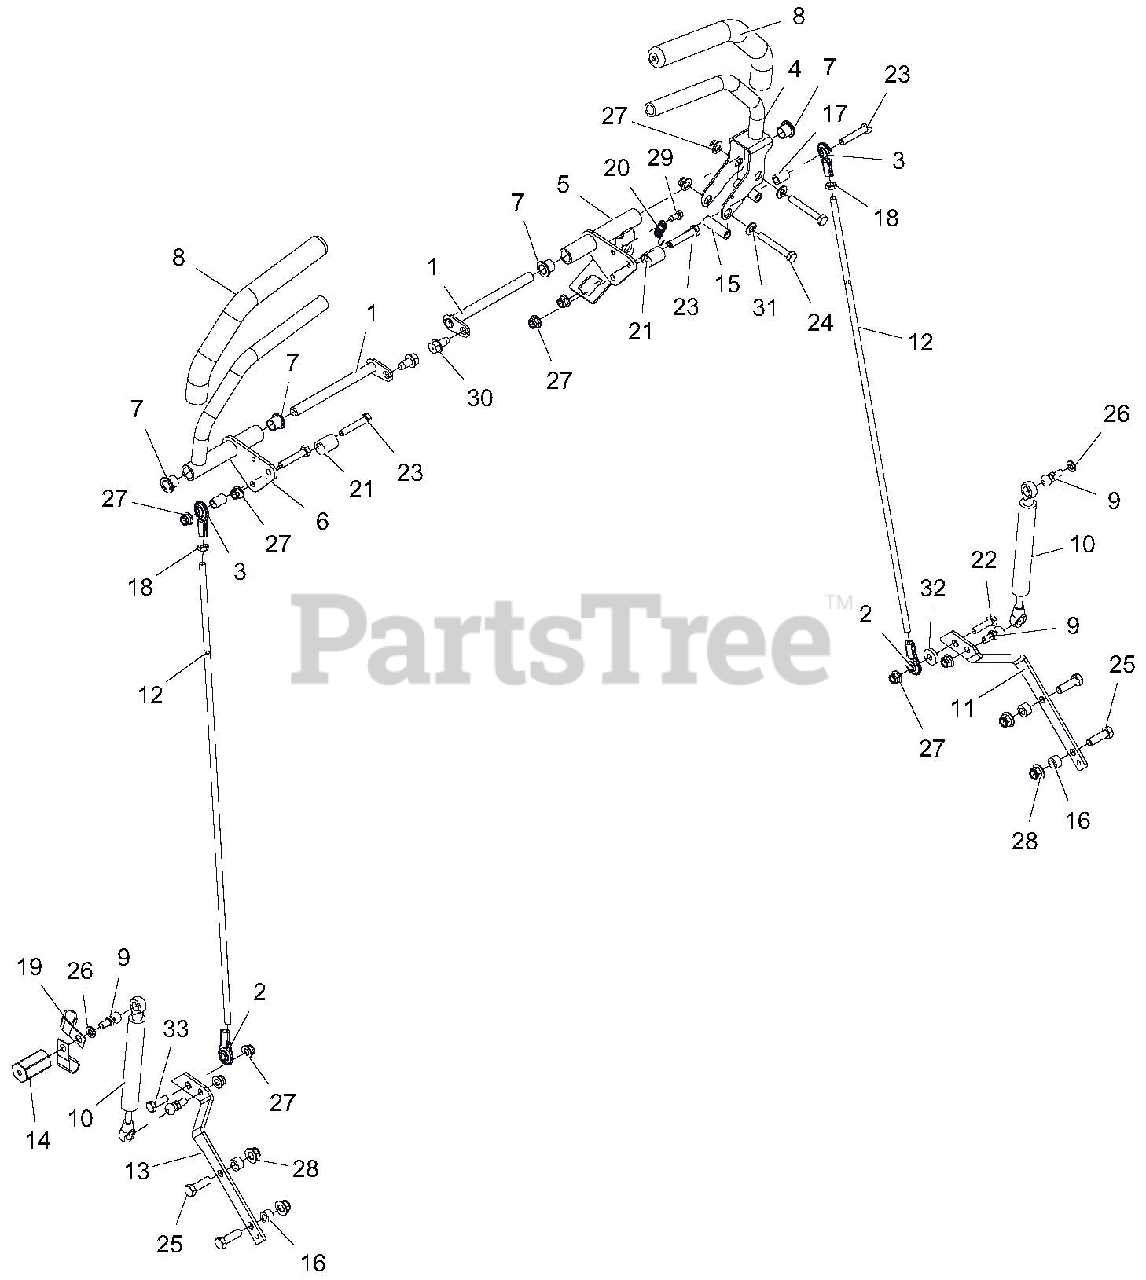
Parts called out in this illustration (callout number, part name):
1	WLDMT, PIN & LOCK
2	ALIGNABALL, 5/16 RH THREAD
3	ALIGNABALL, 5/16 LH THREAD
4	CONTROL, ARM , LH
5	WLDMT, CONTROL MOUNT (LH)
6	WLDMT, CONTROL ARM (RH)
7	BRG, FLG .500 X .620 X .500 BRNZ
8	GRIP, HANDLEBAR REV
9	STUD-BALL
10	CONTROL DAMPER
11	BRKT, CONTROL LH
12	ROD, STEERING
13	BRKT, PROSTANCE CONTROL-RH
14	SPCR, DAMPER PROSTANCE
15	BSHG, SLV .33X.50X1.56
16	BSHG, SLV REV
17	BSHG-SLV .328X.50X.75
18	NUT, JAM -LH .31-24 YWZC
20	SPRG, EXTENSION
21	ECCENTRIC
22	BLT-HEX .31-18X1.25 GR5 YWZC
23	BLT-HEX .31-18X1.75 GR5 YWZC
24	BLT-HEX .31-18X2.25 GR5 YWZC
25	BLT-HEX .38-16X1.25 GR5 YWZC
26	WSHR-LK .31X.078 REG YWZC
27	NUT-LK-NYL-FLG .31-18 YWZC
28	NUT-LK-NYL-FLG .38-16 YWZC
29	SCR-TAP .25-20X.50 HWH TR YWZ
30	SCR-TAP .38-16X.75 HWH TR YWZ
31	WSHR-FL-STL.344X.688X.065YWZC
32	WSHR-FL-STL .328X.87X.179 YWZC
33	BLT-HEX .31-18X1.00 GR5 YWZC
